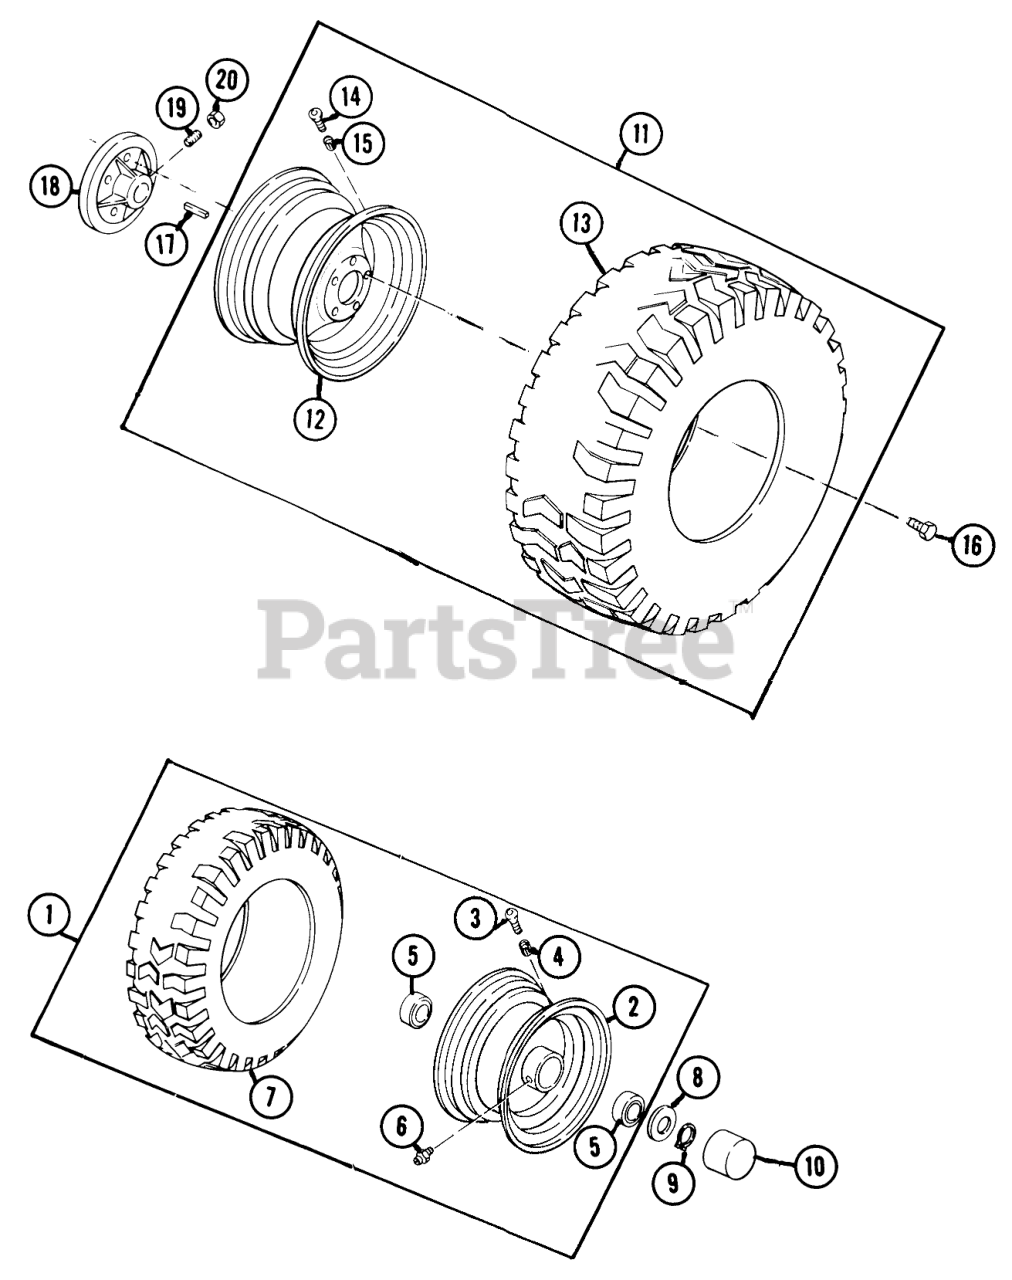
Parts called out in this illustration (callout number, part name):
3	Valve
4	Cap, Valve
7	Tire, Front
13	Tire, 23 x 8.50-12,Rear
15	Cap, Valve
